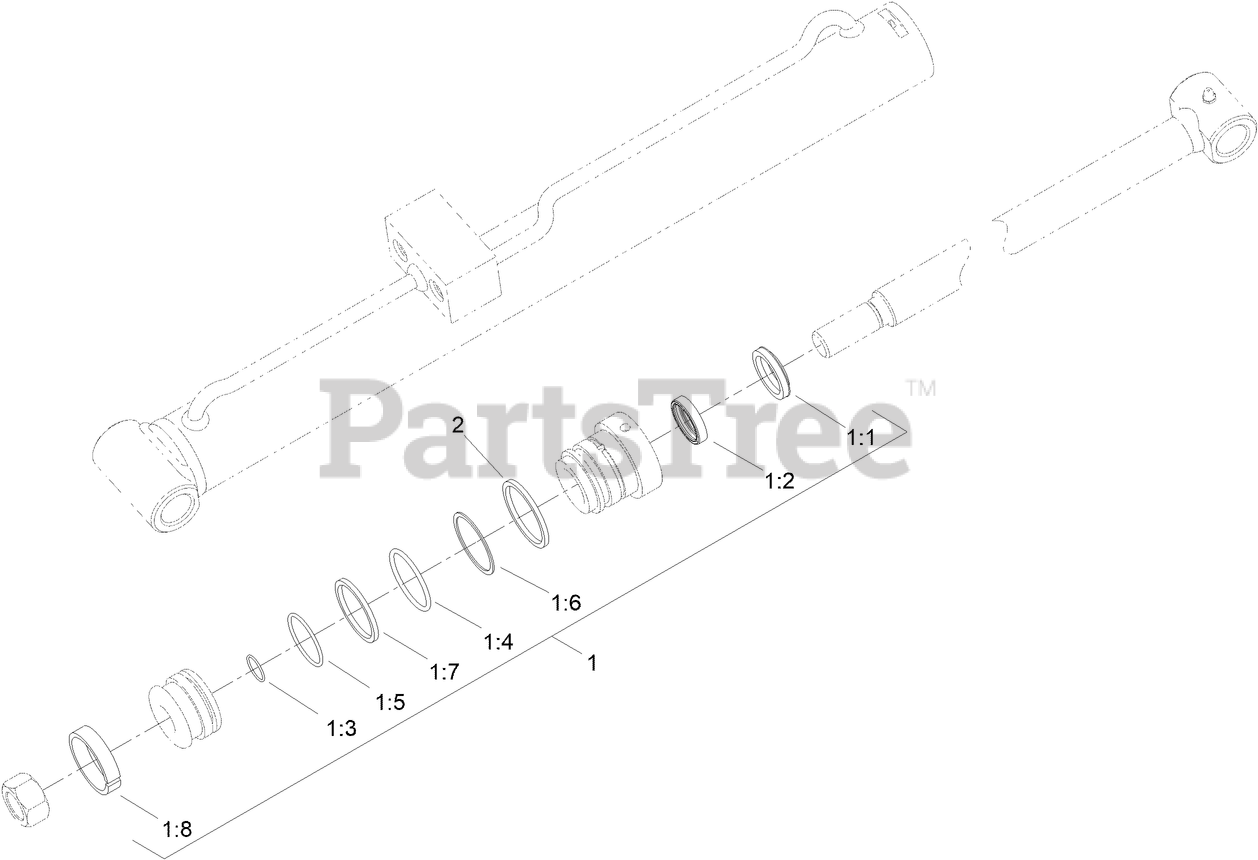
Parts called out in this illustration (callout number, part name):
1	SEAL KIT
1:1	Wiper
1:2	Seal ASM
1:3	Seal-Dust
1:4	Seal-Dust
1:5	Seal-Dust
1:6	Back-up
1:7	Seal ASM
1:8	Ring-WEAR
2	RING - RETAINING
